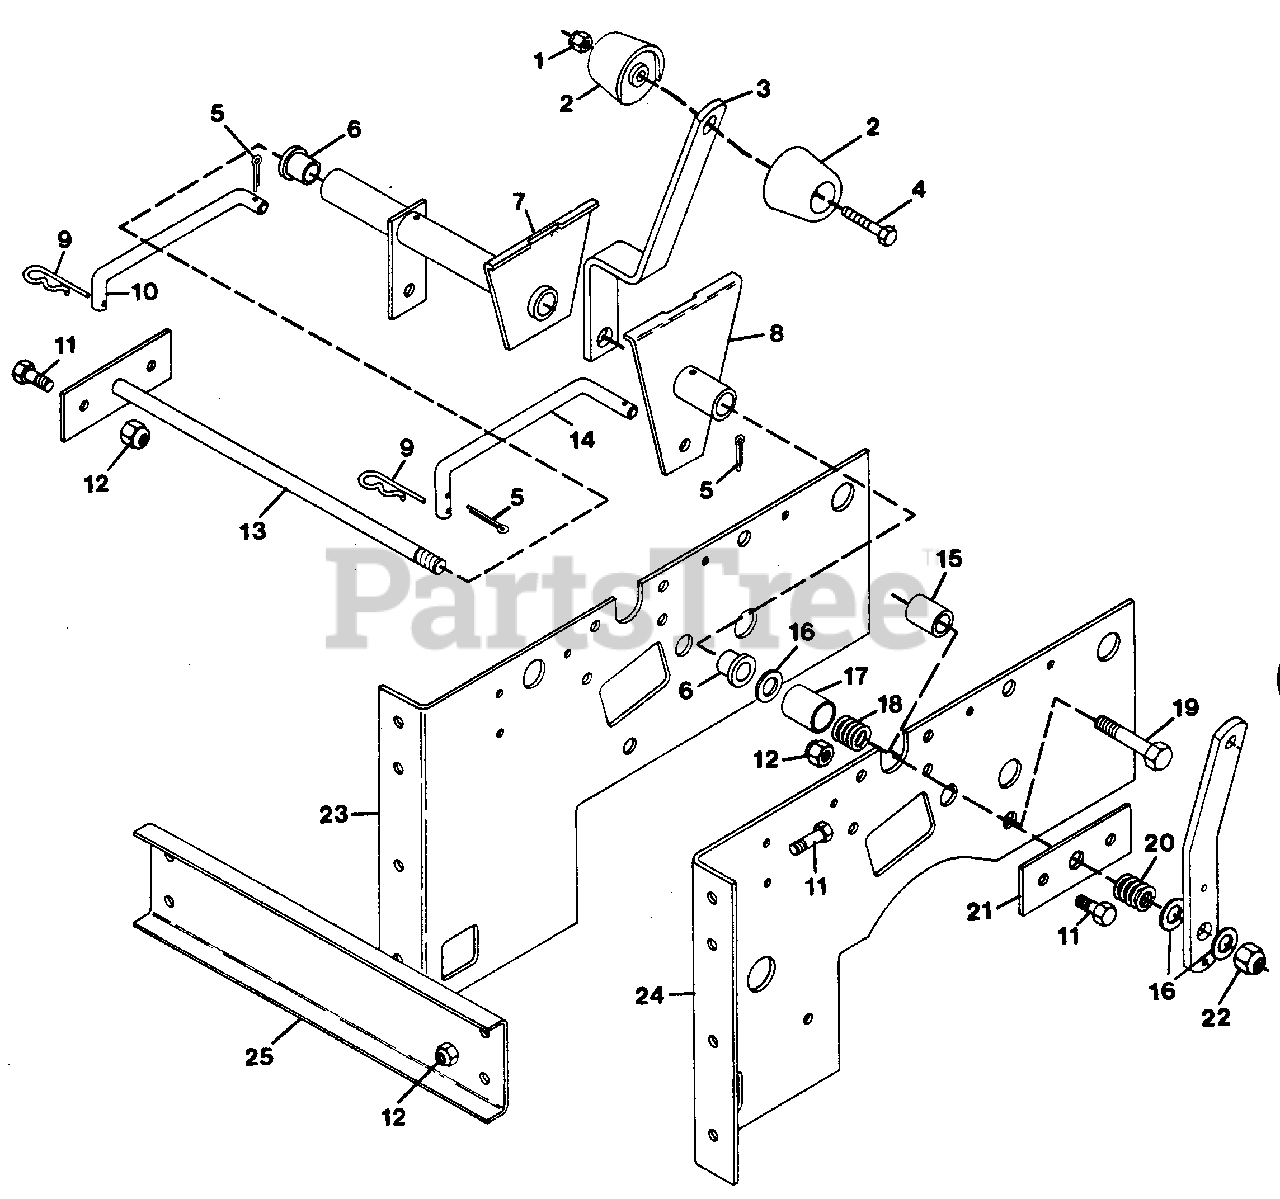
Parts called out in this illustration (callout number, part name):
1	Nut, Lock 1/4-20
2	Knob, Control
3	Lever, Shifter
4	Bolt, Hex 1/4-20x1.50
5	Pin, Cotter .09x.75
6	Bushing, Cable Guide Pulley
7	Weldment, Shift Lever L.H.
8	Weldment, Shift Lever R.H.
9	Pin, Cotter Hair
10	Rod, Gear Shift
11	Bolt, Hex 3/8-16x.875
12	Nut, Lock 3/8-16
13	Weldment, Cross Shaft
14	Rod, Gear Shift
15	Bushing, .505x.750x1.00
16	Washer, Flat .531x1.062x.095(4-Spd)
16	Washer, Flat .531x1.062x.095(8-Spd)
17	Spacer, #2 Shaft
18	Spring, Comp. 2.75x.625x34 Rate
19	Bolt, Hex 1/2-13x2.00
20	Spring, Comp. 1x.78x338 Rate(4-Spd)
20	Spring, Comp. 1x.80x36 Rate(8-Spd)
21	Plate, Cross Shaft(4-Spd)
22	Nut, Lock 1/2-13
23	Bracket, Control Mount R.H.
24	Bracket, Control Mount L.H.
25	Bracket, Hydraulic Tank
